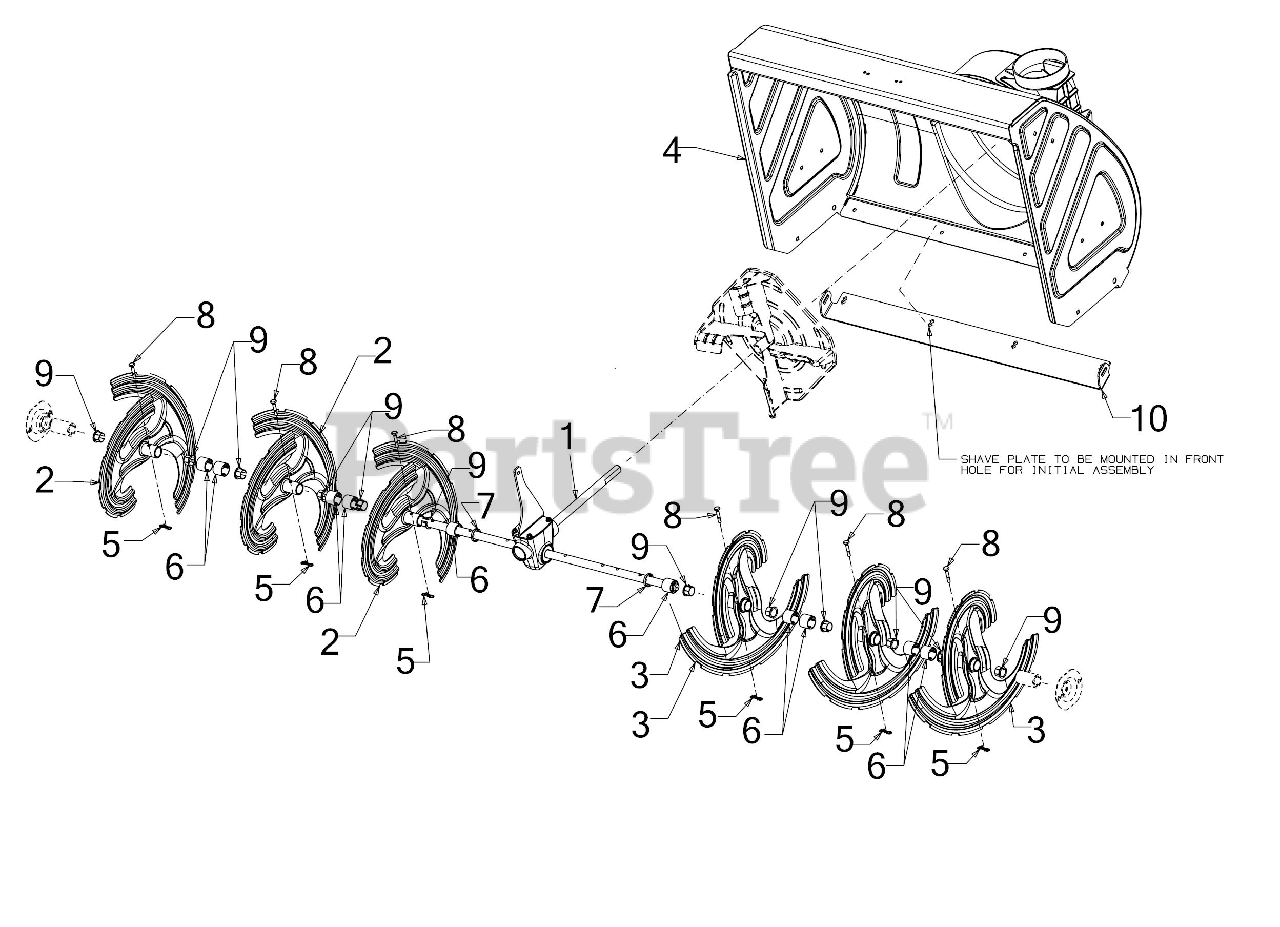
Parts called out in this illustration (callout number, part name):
1	34" AUGER GEARBOX ASSEMBLY
5	BOW TIE COTTER PIN 1/4-5/16
6	SPACER 1.25OD x .75ID X1.00 LG
7	SPCR 1.25 OD x 75IDX2.00LG
8	SHEAR PIN .25 x 1.50 GR2
8	Cub Cadet SHEAR PINS (2X SNOW)
8	SHEAR PINS QTY 4
9	FLANGE BUSHING
